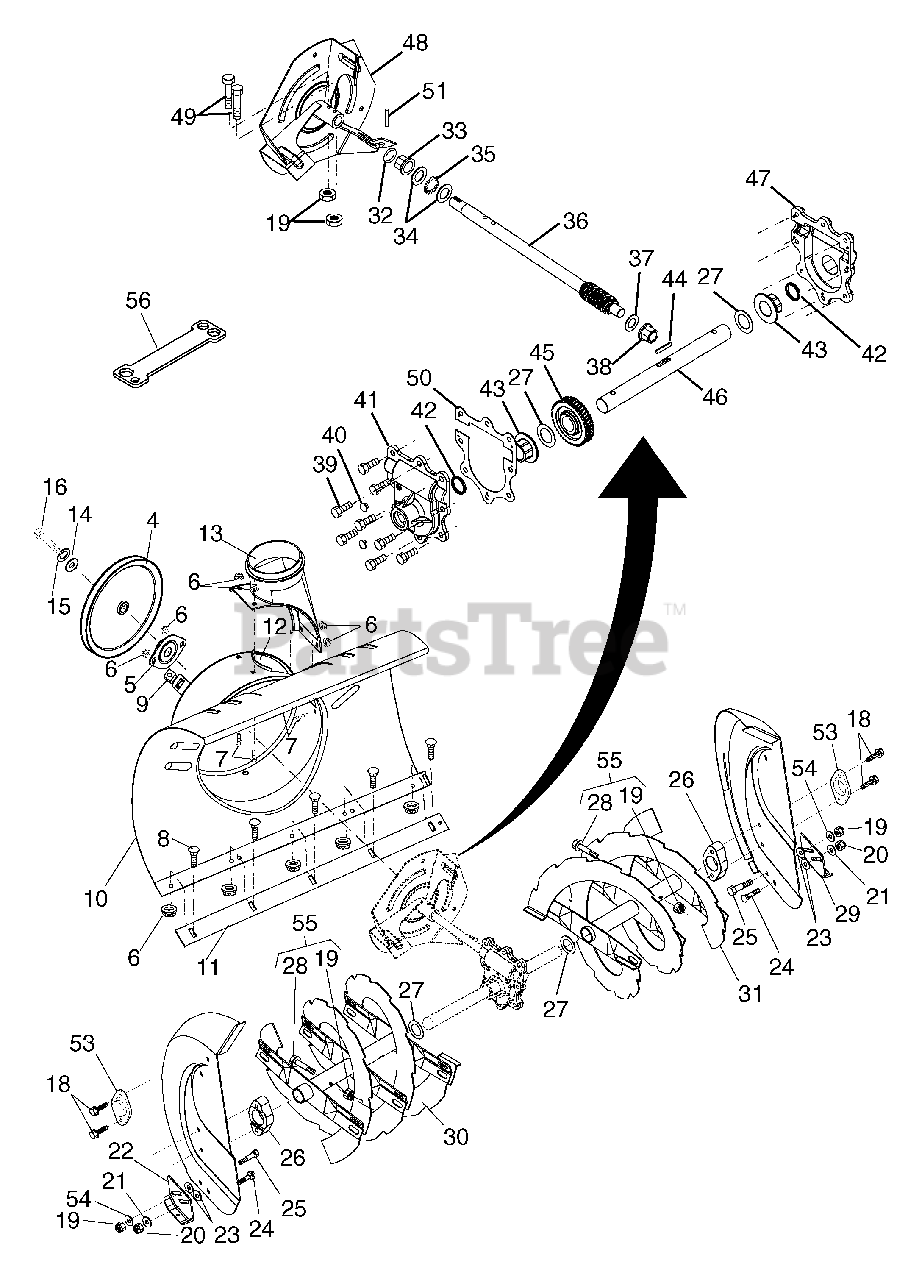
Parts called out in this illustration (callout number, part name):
4	Pulley, Impeller
5	Bearing Assembly, Flange
6	Nut, Hex Flange 5/16-18
7	Bolt, Flat Head, Carriage 5/16-18 x 5/8
8	Bolt, Carriage 5/16-1 8 x 5/8
9	Nut, Cage 3/8-16
10	Housing, Auger
11	Bar, Scraper
12	Bracket, Corner Discharge
13	Base, Discharge Chute
14	Washer, Flat
15	Washer, Lock 5/16
16	Screw, Hex Head 5/16-18 x 3/4
18	Screw, Hex Head 5/16 x 1
19	Nut, Hex Lock 1/4-20
20	Nut, Hex Lock 5/16-18
21	Washer, Flat 5/16
22	Skid Plate, RH
23	Washer, Nylon, Friction
24	Bolt, Carriage 5/16-18 x 3/4
25	Bolt, Shoulder 1/4-20
26	Bearing Retainer, Plastic
27	Washer, Thrust, 1"
28	Bolt, Shear
29	Skid Plate, LH
30	Auger Assembly, RH
31	Auger Assembly, LH
33	Bushing, Flange 3/4
34	Washer, Thrust 3/4
35	Bearing, Thrust 3/4
36	Shaft, Impeller
37	Washer, Thrust 5/8
38	Bushing, Flange 5/8
39	Screw, Hex Head 5/16-18 x 3/4
40	Plug, Case
41	Housing, Gearbox, RH
43	Bushing, Flange, 1"
44	Key, Square 1/4 x 1/4 x 7/8
45	Gear, Worm
46	Shaft, Auger
47	Housing, Gearbox, LH
48	Impeller Assembly
49	Screw, Hex Head 1/4-20 x 1-5/8
50	Gasket, Gearbox
51	Pin, Roll 3/16 x 1-1/8
53	Bearing, Auger
54	Washer, Flat 1/4
55	Kit, Shear
56	Multi-Wrench
